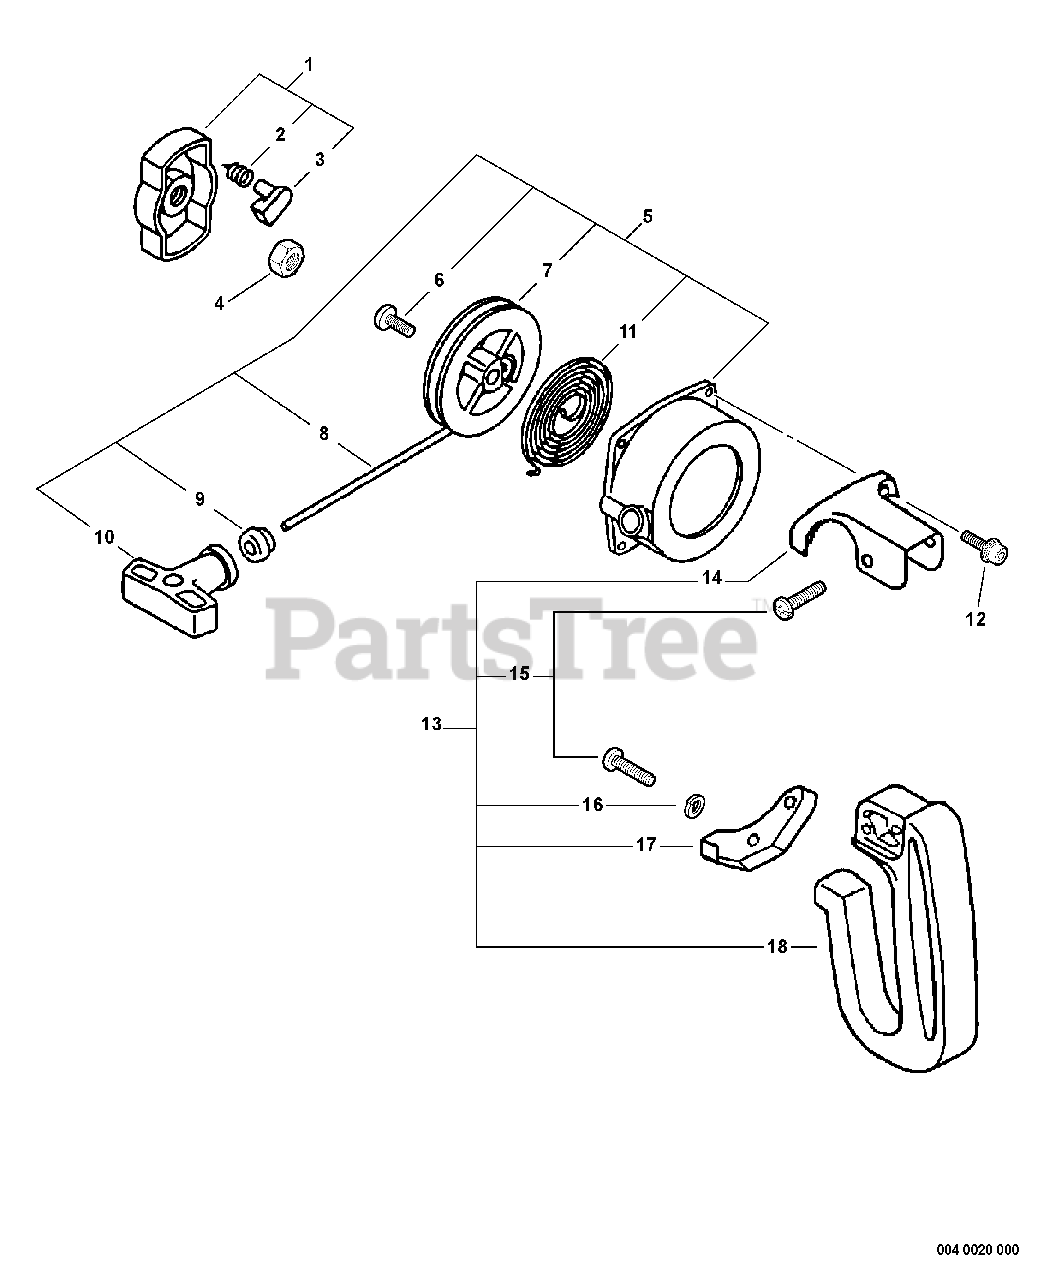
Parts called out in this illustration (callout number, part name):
1	STARTER PAWL ASSY
2	SPRING, RETURN
3	PAWL, STARTER - BLACK
5	STARTER ASSY
7	REEL, ROPE
8	ROPE, STARTER - 3X1000
9	GUIDE, ROPE
10	GRIP, STARTER
11	SPRING, REWIND
12	SCREW - 4X16
13	HANDLE ASSY - REAR
14	BRACKET, HANDLE - UPPER
15	SCREW - 5X16 -- TAPPING
16	LOCKWASHER - 5
17	BRACKET, HANDLE - LOWER
18	HANDLE - REAR
